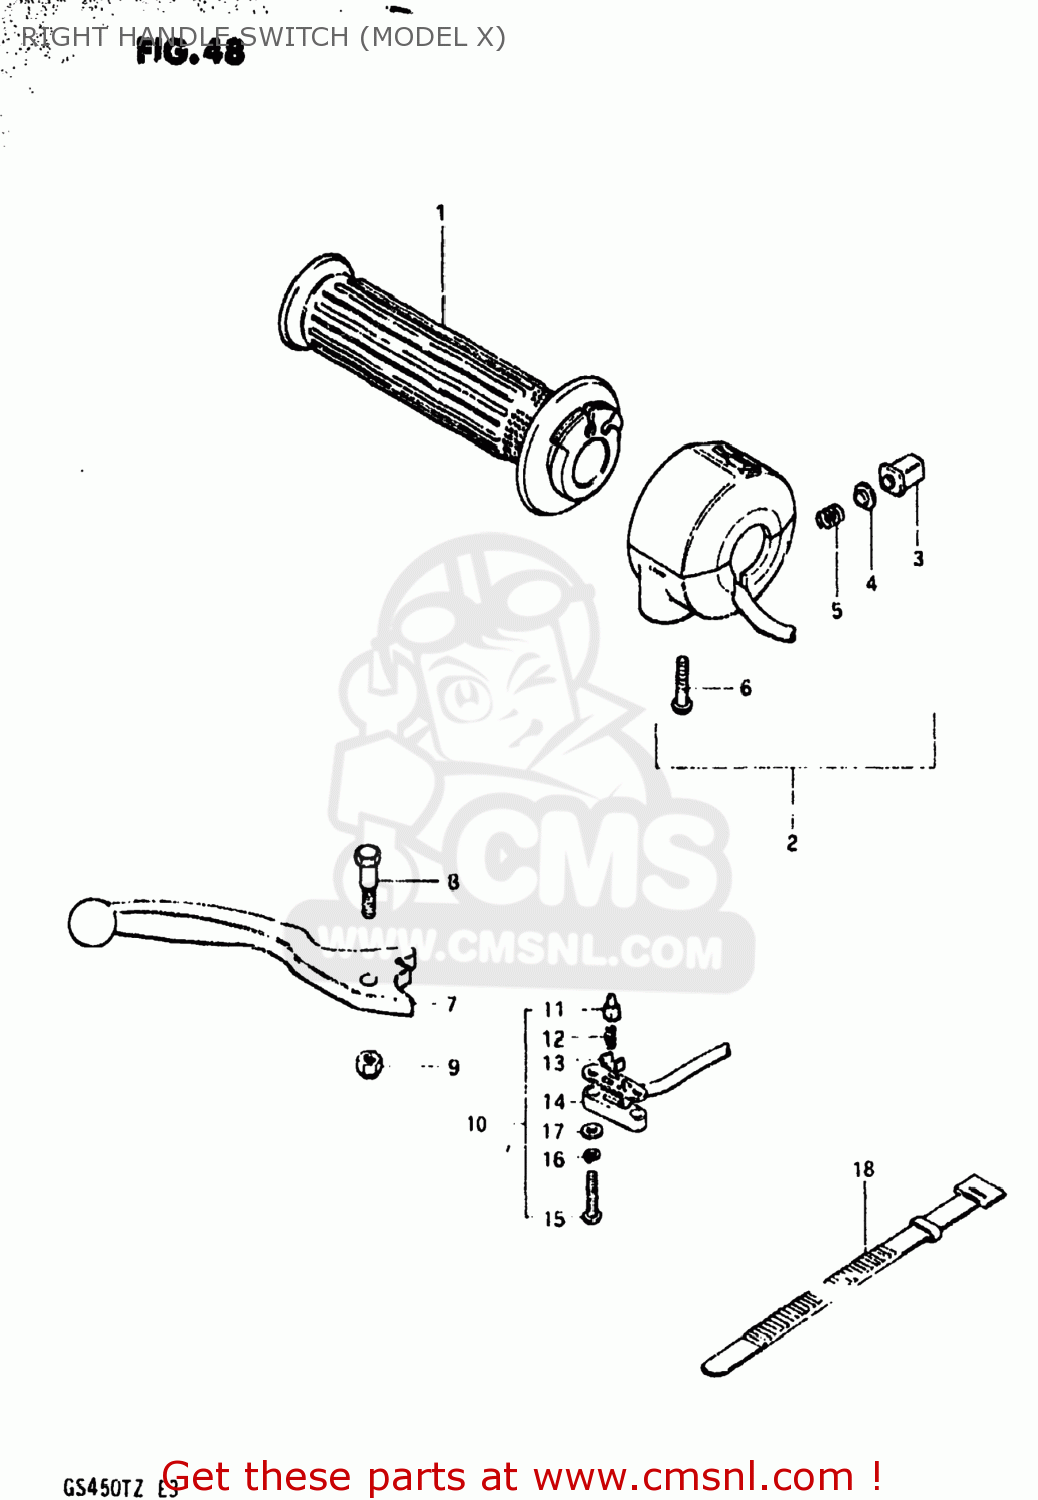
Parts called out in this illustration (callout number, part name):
1	GRIP,THROTTLE
2	CASE ASSEMBLY,THROTTLE
3	BUTTON,HORN
4	CONTACT
5	SPRING
6	SCREW
7	LEVER,BRAKE
8	BOLT
9	NUT 6MM
10	SWITCH ASSEMBLY
11	HOLDER
12	SPRING
13	PLATE
14	COVER,FR BK TERMINAL BASE
15	SCREW
16	LOCK WASHER
17	WASHER
18	CLAMP(L:120)
